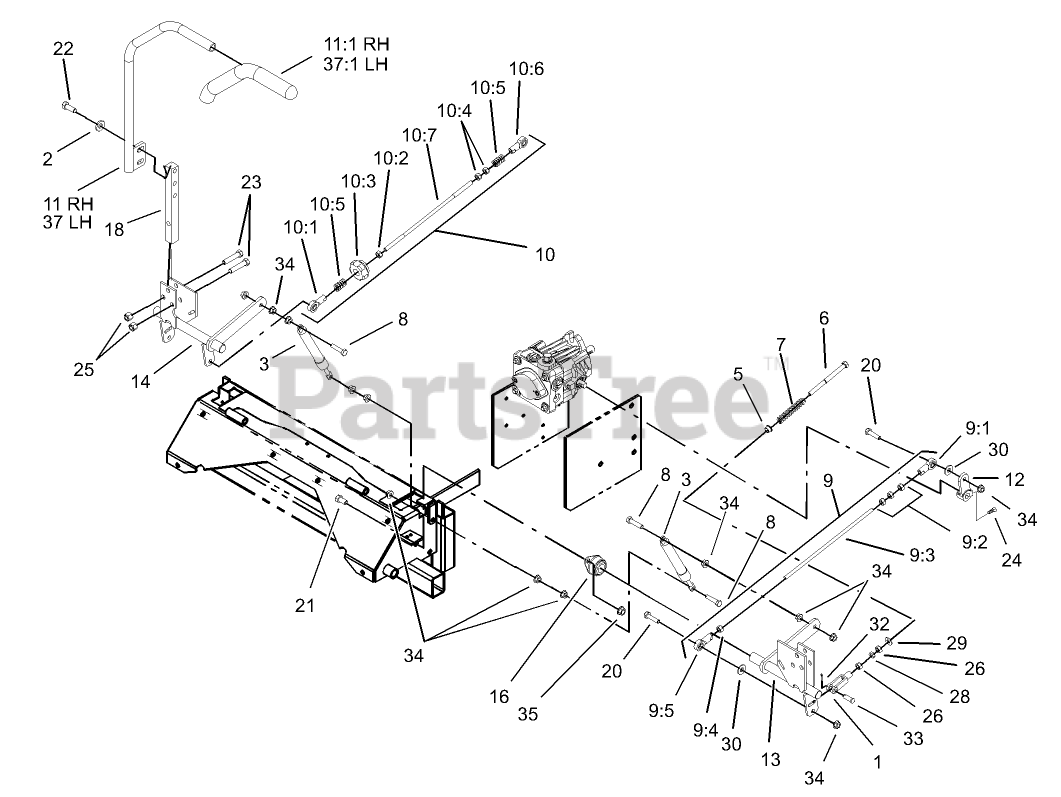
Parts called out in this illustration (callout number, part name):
1	YOKE-ADJUSTABLE
2	WASHER-BELLEVILLE
3	Damper-Control, Motion
5	BUSHING-FLANGED
6	BOLT-RETURN, NEUTRAL
7	SPRING-RETURN, NEUTRAL
8	SCREW-HH
9	LH Pump Linkage ASM
9:1	BALLJOINT-RH
9:2	NUT-HEX
9:3	Link-Rod, Tracking
9:5	BALLJOINT-LH
10	Tracking Rod ASM
10:1	BALLJOINT-RH
10:2	NUT-HEX
10:3	KNOB-TRACKING
10:5	SPRING-COMPRESSION
10:6	BALLJOINT-LH
10:7	Link-Rod, Tracking
11	RH LEVER ASM
11:1	GRIP-CONTROL, MOTION
12	ARM-CONTROL, PUMP
13	CONTROL-MOTION, LH
14	CONTROL-MOTION, RH
16	BEARING-FLANGE, SIDE
18	ARM-SHAFT, CONTROL
20	SCREW-HH
21	SCREW-HH
22	SCREW-HH
23	SCREW-HH
24	SCREW-SET
25	NUT-LOCK, NI
26	NUT-HEX
28	NUT-JAM
29	WASHER-FLAT
30	WASHER-FLAT
32	PIN-COTTER
33	PIN-CLEVIS
34	NUT-HF
35	NUT-HHF, WHIZ
37	LH LEVER ASM
37:1	GRIP-CONTROL, MOTION
